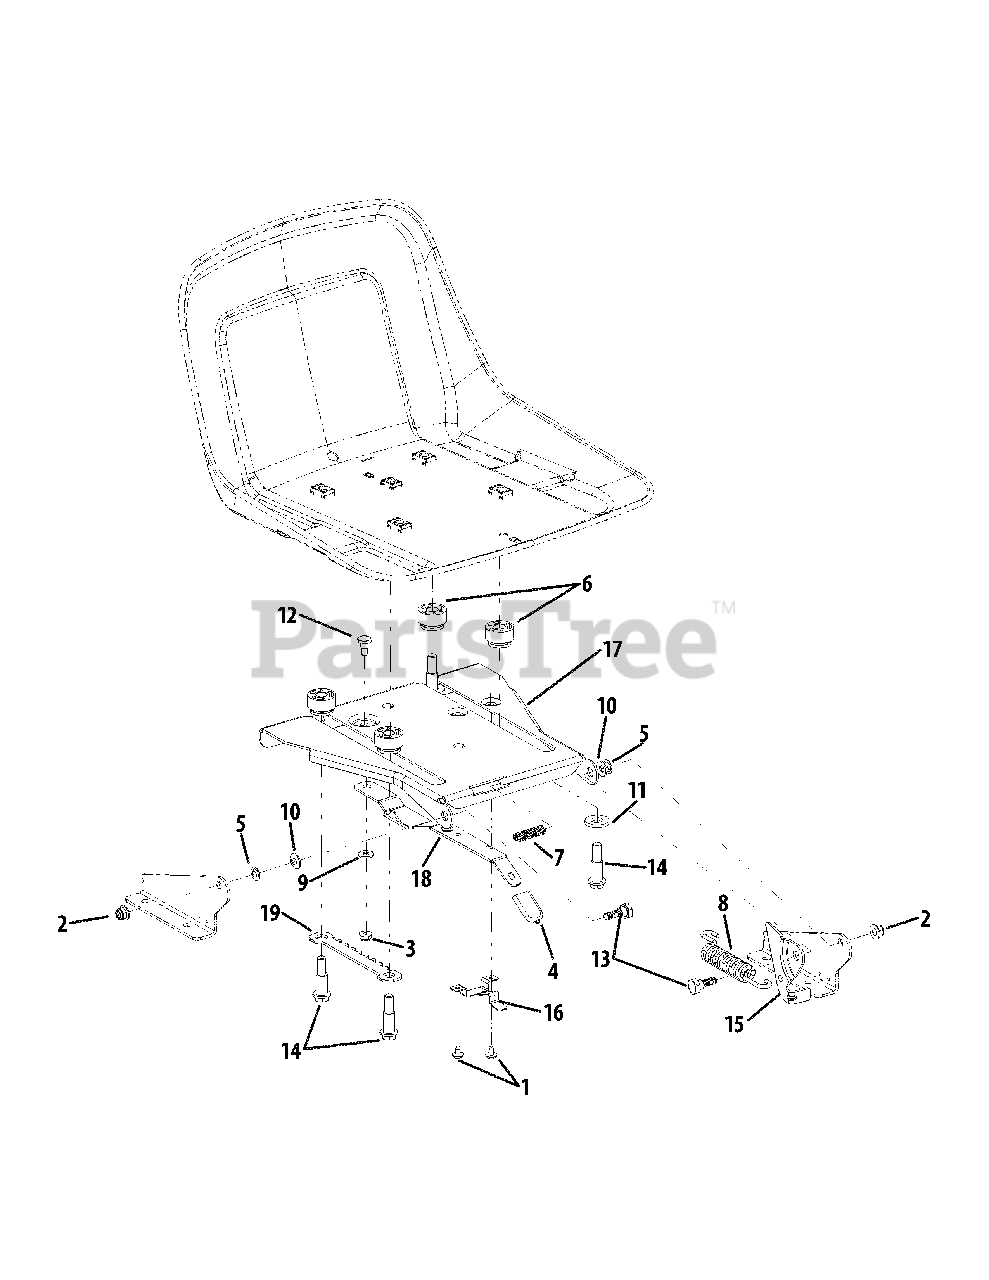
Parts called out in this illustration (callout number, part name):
1	Hex Hd. Wshr Screw, #10-16 x .375
2	Flangelock Nut, 5/16-18
3	Flangelock Nut, 1/4-20
4	Seat Adjustment Grip
5	Speed Nut, .3125
6	Seat Adjustment Spacer
7	Compression Spring, .41 x 1.50
8	Extension Spring, .84 x 4.6
9	Flat Washer, .344 x .62 x .033
10	Bell Washer, .340 x .872 x .060
11	Flat Washer, .531 x 1.062 x .134
12	Shoulder Screw, .340 x .285 x 1/4-20
13	Shoulder Screw, .437 x .268 x 5/16-18
14	Shoulder Bolt, .50 x .925 x 3/8 -16
15	Seat Lift Bracket
16	Seat Adjustment Stop
19	Seat Adjustment Selector
